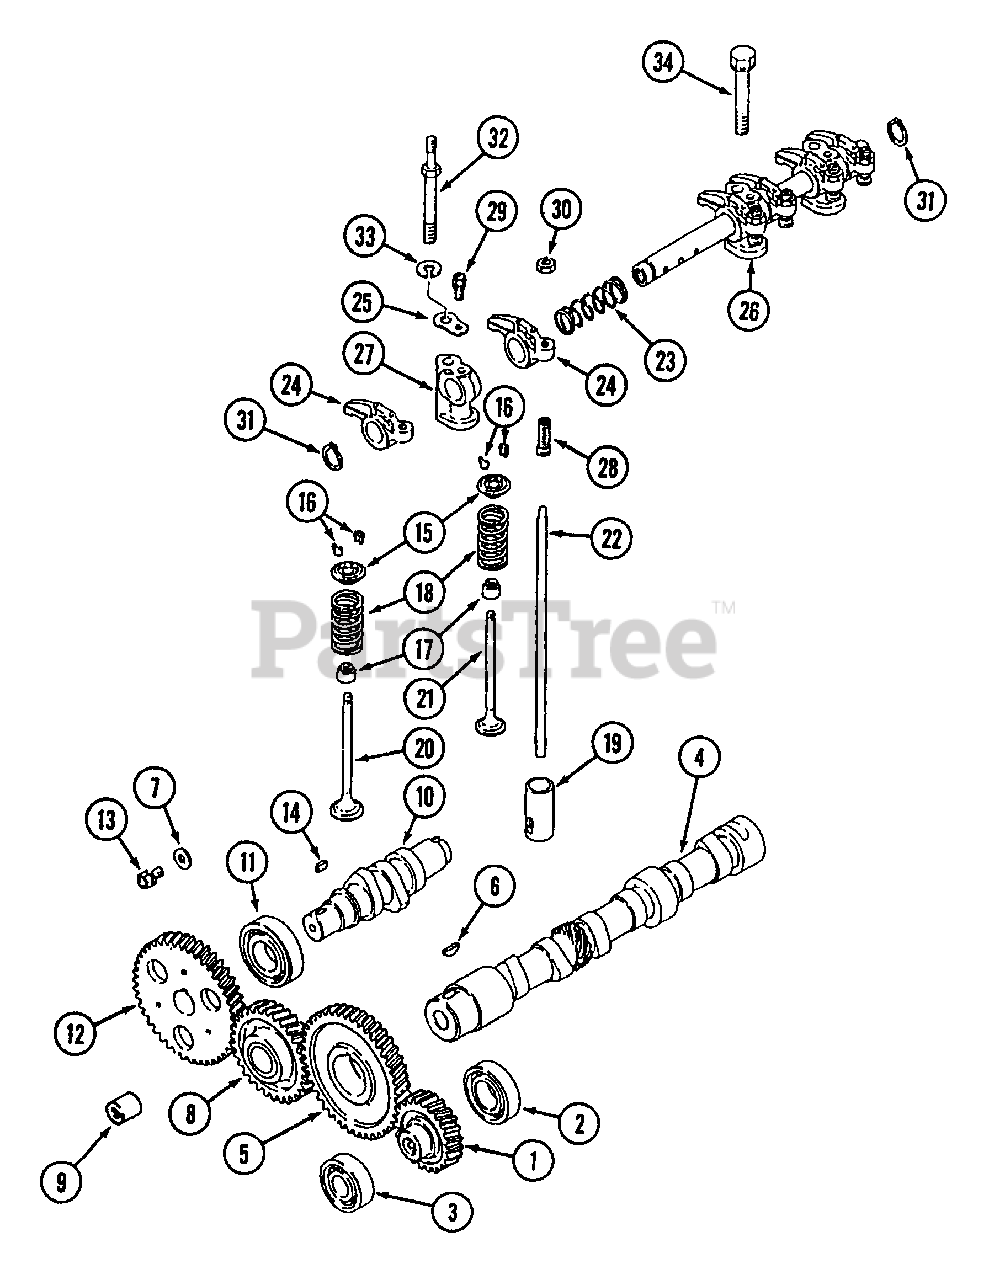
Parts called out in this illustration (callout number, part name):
1	Gear Press Oil Pump
2	Bearing, Ball
3	Bearing, Ball
5	Gear, Camshaft
6	Key, Woodruff
8	Idler Gear Ass'y.
9	Bushing, Idler Gear
10	Camshaft, Inj. Pump
11	Bearing, Ball
12	Gear, Inj. Pump
13	Bolt,
15	Retainer, Valve Spring
16	Lock, Retainer
17	Seal, Valve Stem
18	Spring, Valve
19	Tappet
20	Valve, Intake
21	Valve, Exhaust
23	Spring, L.H. Rocker Shaft
24	Arm, Rocker
25	Washer, Seat
26	Rocker, Shaft Ass'y.
27	Stay, Rocker
28	Screw, Adjusting
29	Bolt,
30	Nut, Jam
31	Ring, Snap
33	Washer, Spring
34	Bolt,
